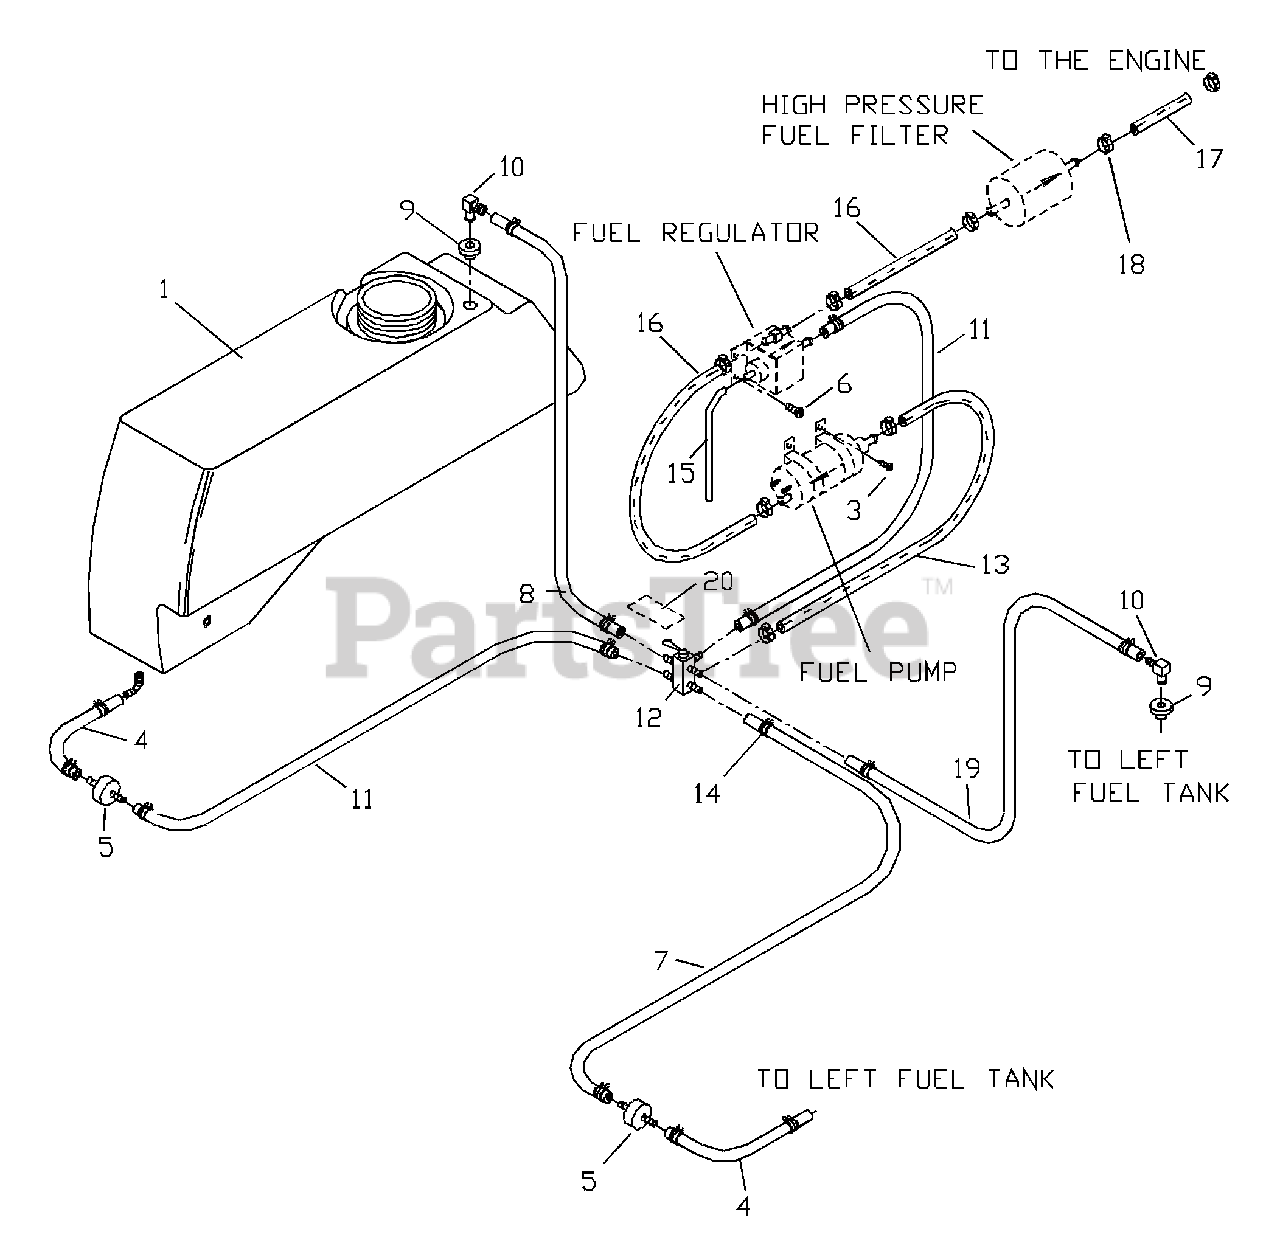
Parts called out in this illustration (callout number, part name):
1	RT. FUEL TANK
3	SELF TAPPING SCREW
6	1/4-20 SELF TAPPING SCREW
7	FUEL LINE
8	FUEL LINE
9	RUBBER GROMMET
11	FUEL LINE
12	FUEL VALVE
13	EFI HOSE
14	HOSE CLAMP
16	EFI HOSE
17	EFI HOSE
20	DECAL, FUEL VALVE
